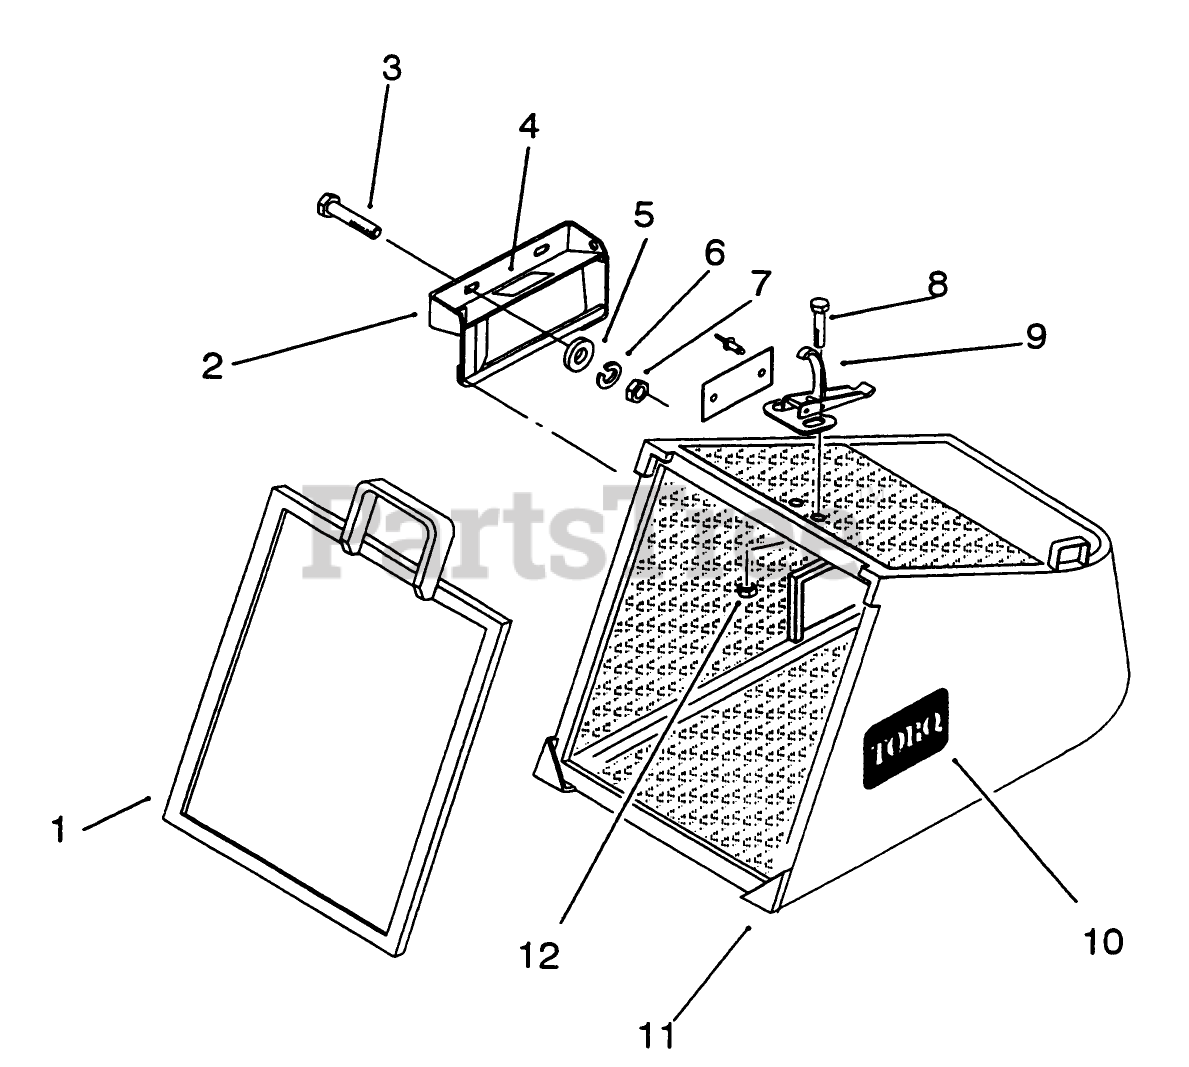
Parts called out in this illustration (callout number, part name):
2	Bracket & Decal (Incl. Ref. #4)
3	SCREW-HH
4	DECAL - DANGER
5	NUT-LOCK, NI
6	WASHER-LOCK
7	NUT-HEX
9	CLAMP-SLOTTED
10	DECAL
12	NUT-HEX, KEPS
